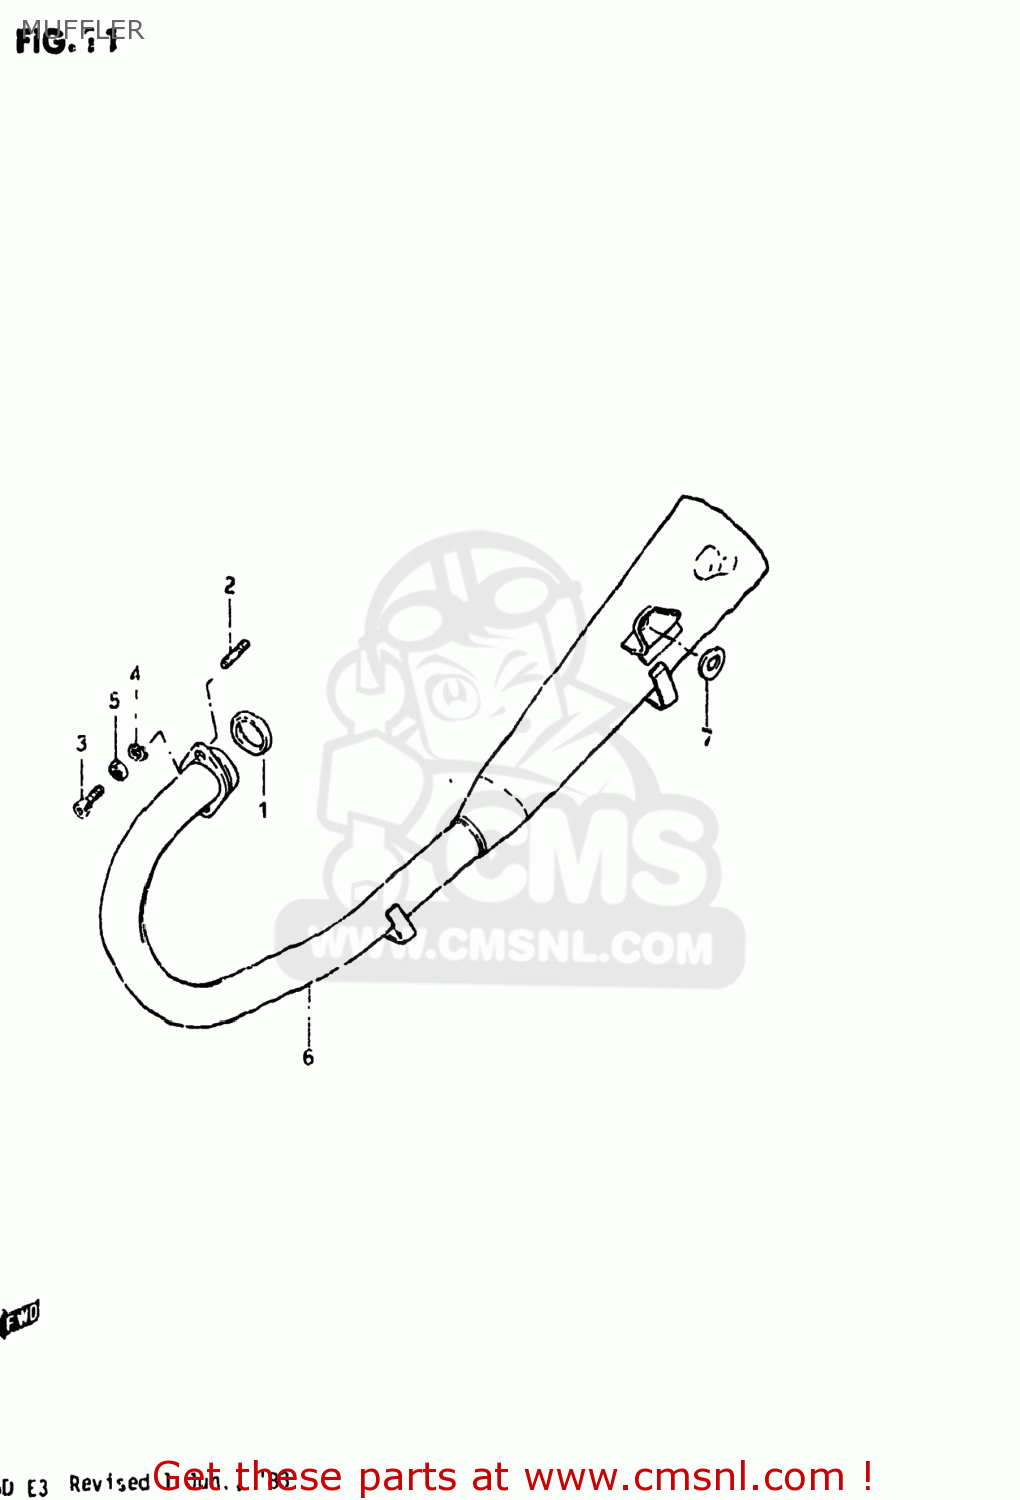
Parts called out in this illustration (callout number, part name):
1	GASKET,EXHAUST PIPE (NAS)
2	STUD 6X20
3	BOLT
4	LOCK WASHER
5	NUT
6	MUFFLER ASSEMBLY
7	WASHER
